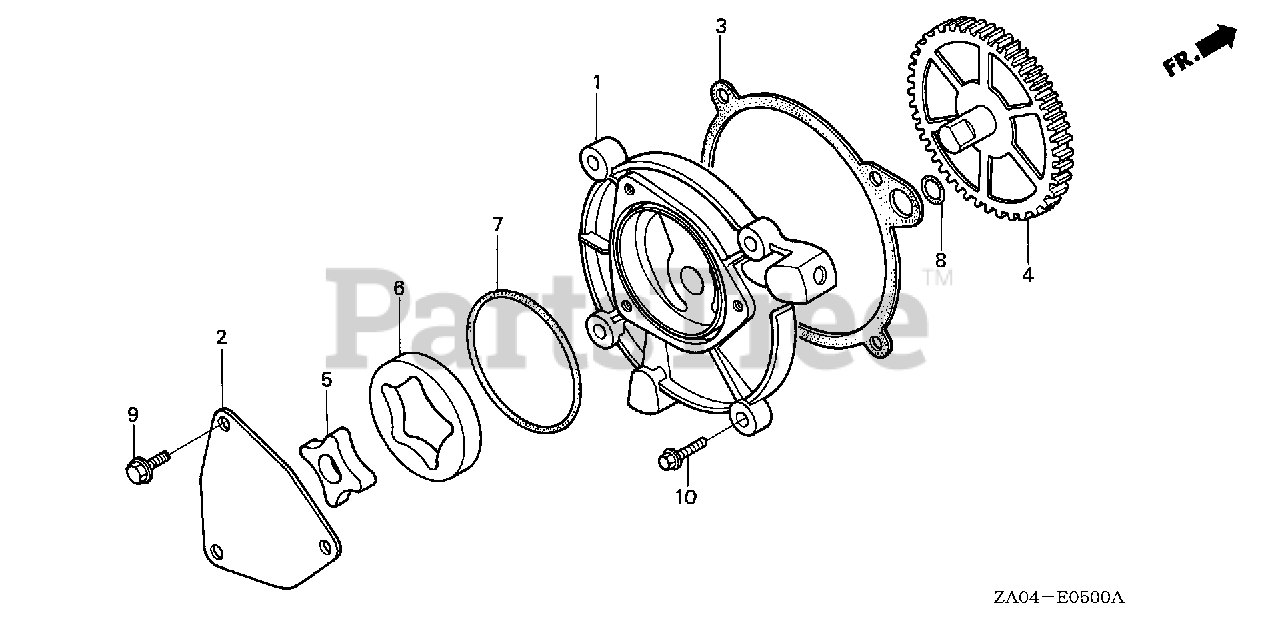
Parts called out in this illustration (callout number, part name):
1	BODY, OIL PUMP
2	COVER, OIL PUMP
3	GASKET, OIL PUMP
4	GEAR ASSY., OIL PUMP
5	ROTOR (INNER)
6	ROTOR (OUTER)
7	O-RING (45X2.5) (ARAI)
8	O-RING (10.8X2.4) (ARAI)
9	BOLT, FLANGE (6X12) Use from Engine SN 2086984.
10	BOLT, FLANGE (6X28)
